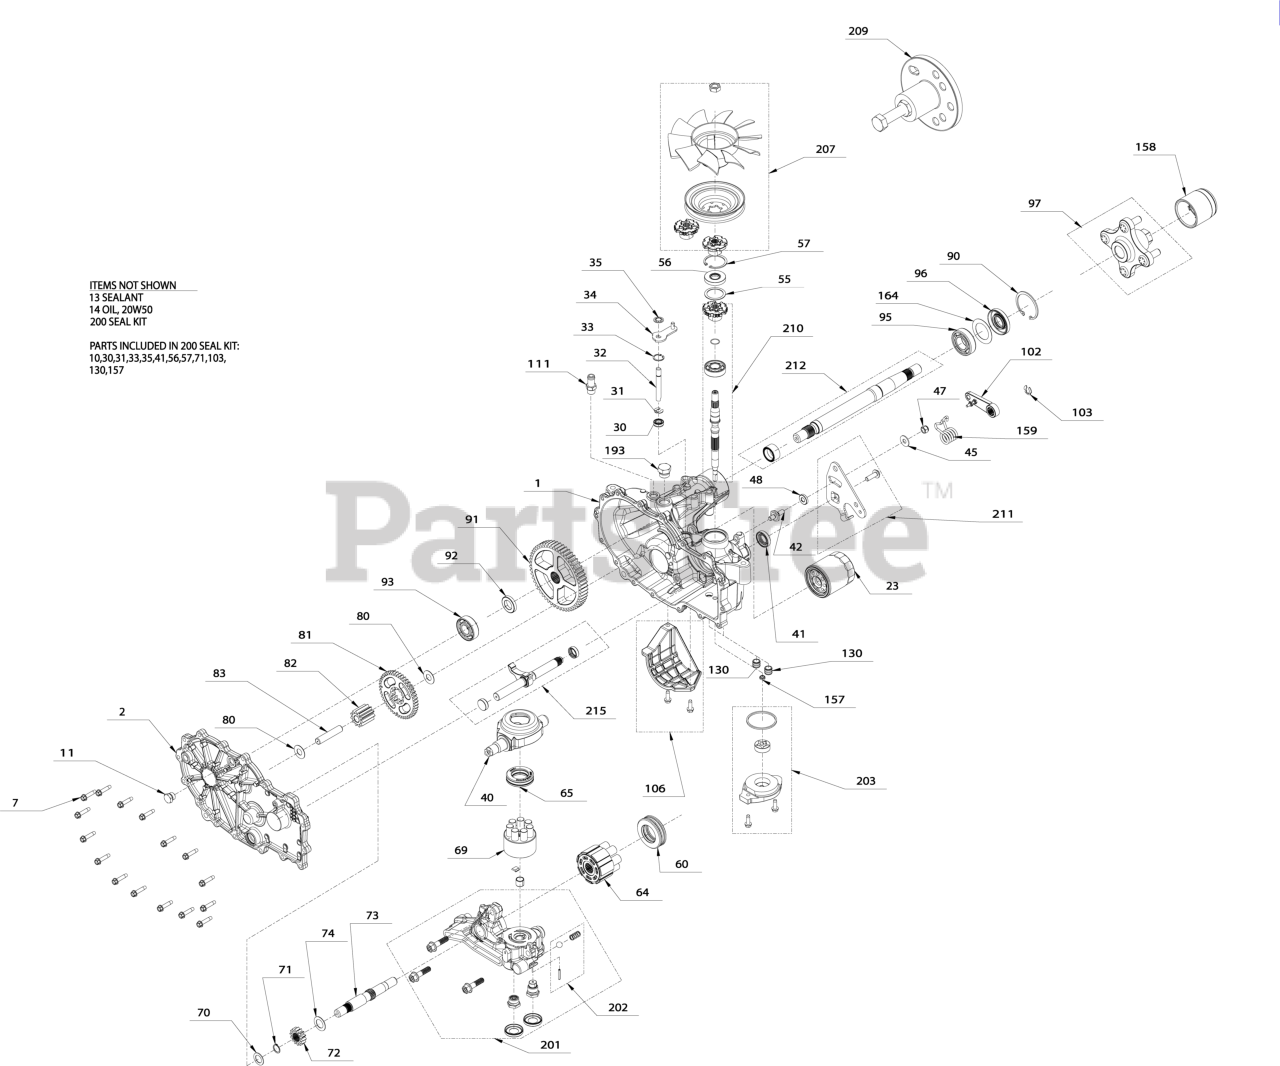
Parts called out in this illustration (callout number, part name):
1	KIT, HOUSING, MAIN, LH, CHRG, CNTL
2	KIT, SIDE COVER, LH
7	SCREW,HEX WASHER 1/4-20X1.125
11	PLUG EXT HEX VENT 9/16 18
13	SEALANT TUBE 10.1OZ.
14	FLUID, HYDRO 15W50 QT
14	FLUID, HYDRO 20W50 QT
23	FILTER, HYDRO-GEAR 2800 TRANS
30	Seal, lip .375 x 375 x 325
31	RING. RETAINING
32	ROD, BYPASS
33	RING, RET .750
34	HG BYPASS ARM (52370)
35	RING, RTNG .
40	TRUNNION, SWASHPLATE
41	SEAL, LIP 18X32X7
42	STUD. SHORT 5/16-24
47	NUT, HEX 5/16-24 NYLON
48	SPACER
55	WASHER 1.23X1.56X.04
56	SEAL, LIP 17X40X7
57	RING, RET 1.56 INT
60	HG THRUST BEARING (51462)
64	HG 16CC CYLINDER BLOCK (71579)
65	BEARING. THRUST 30 X 52 X 13
69	ASSY, BLOCK 7 PISTON
71	RING, RET 62 EXT
73	SHAFT, MOTOR
74	WASHER .71 X 1.16 X .04
80	WASHER .5X1.0X.032
81	GEAR 45 TOOTH
83	JACK SHAFT (PIN)
90	RING, RETAINING
91	GEAR 54 TOOTH
92	SPACER
93	KIT, BEARING
95	BEARING, BALL 25.4 X 52 X 15
96	SEAL, LIP
97	KIT, HUB 4 BOLT
102	BRAKE ARM HG 71957
103	CLIP,BRAKE ARM HYDROGEAR 52027
106	KIT, FILTER GUARD
111	KIT, FITTING 1/2 BEADED 9/16
130	TUBE CHARGE TRIPLE ORING
157	KIT GEROTOR SEAL
158	CAP, AXLE
159	SPRING, TORSION, CW
164	WASHER, 1.355 x 2.035 x .021 FLAT
201	KIT, CENTER SECTION, LH CHARGE
202	KIT CHARGE RELIEF
203	KIT, CHARGE
207	KIT, FAN / PULLEY
209	HUB PULLER 5 BLT
210	KIT INPUT SHAFT
211	KIT, CONTROL ARM
212	KIT SHAFT AXLE
215	KIT, OUTBOARD, RH ROT B / LH ROT A
